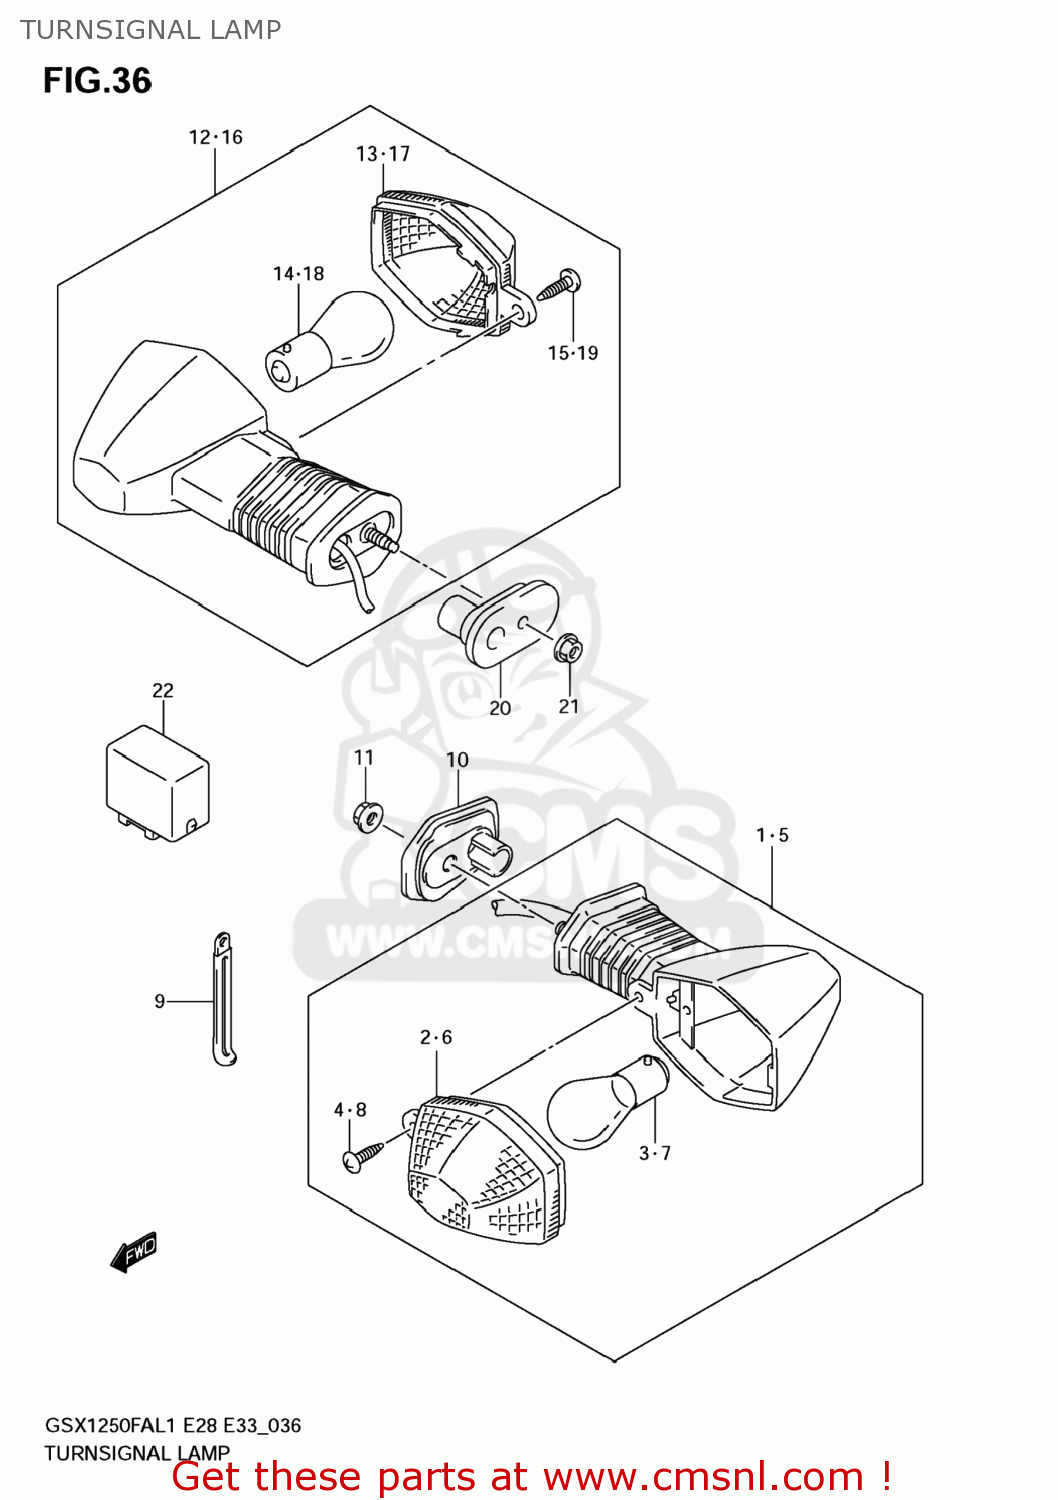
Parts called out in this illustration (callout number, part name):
1	LAMP ASSY,FR TURN SIGNAL,R
2	LENS
3	BULB(12V21W,AMBER)
4	SCREW
5	LAMP ASSY,FR TURN SIGNAL,L
6	LENS
7	BULB(12V21W,AMBER)
8	SCREW
9	CLAMP(L:45)
10	PLATE,FR TURNSIGNAL
11	NUT
12	LAMP ASSY,RR TURNSIGNAL,R
13	LENS
14	BULB(12V21W,AMBER)
15	SCREW
16	LAMP ASSY,RR TURNSIGNAL,L
17	LENS
18	BULB(12V21W,AMBER)
19	SCREW
20	PLATE,TURNSIGNAL LAMP
21	NUT
22	RELAY ASSY,TURNSIGNAL LAMP
